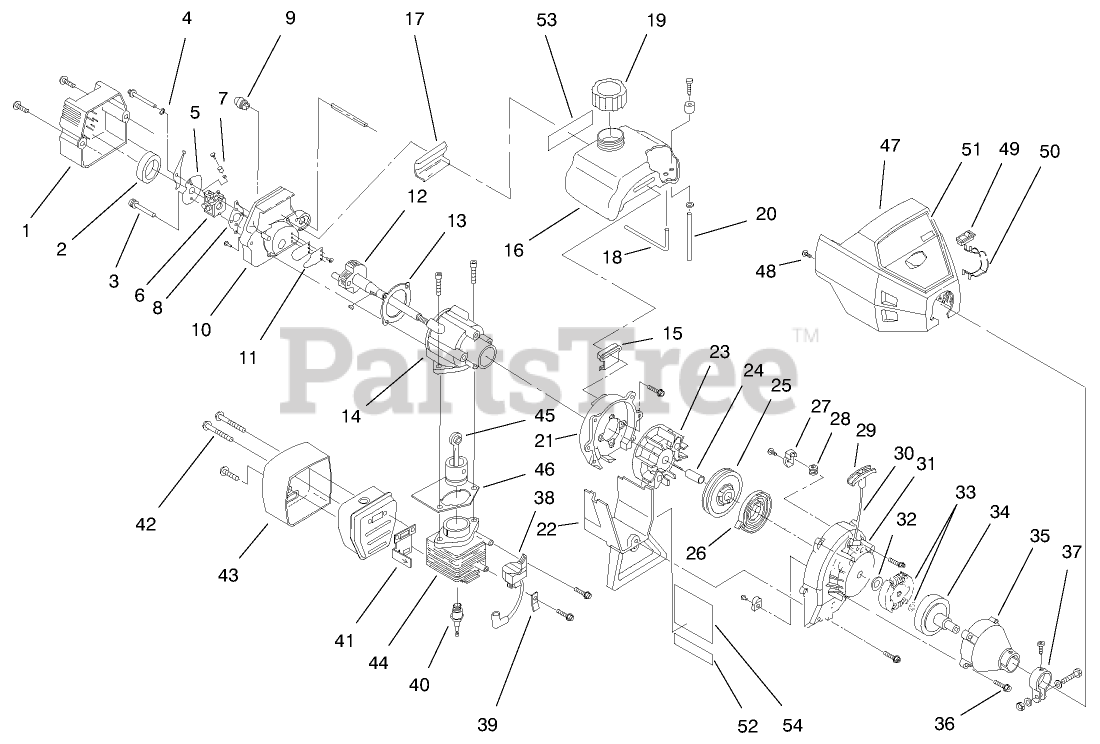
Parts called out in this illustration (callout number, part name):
1	Plate-Logo
2	Plate-Engine Logo
3	NUT-JAM
4	GASKET-AIR CLEANER
5	Air Cleaner Assembly (Incl. Ref. #6, 8 & 9)
6	WASHER-FLAT
7	HEX FL HD M.6X1.0X25MM
8	NUT-HEX
9	AIR CLEANER COVER WA
10	SPIT BACK DEFLECTOR
11	5/16 ID BSHG
12	NUT-LOCK
13	SCREW-HHF
14	FILTER
15	AIR CLEANER COVER
16	AIR CLEANER GUARD
